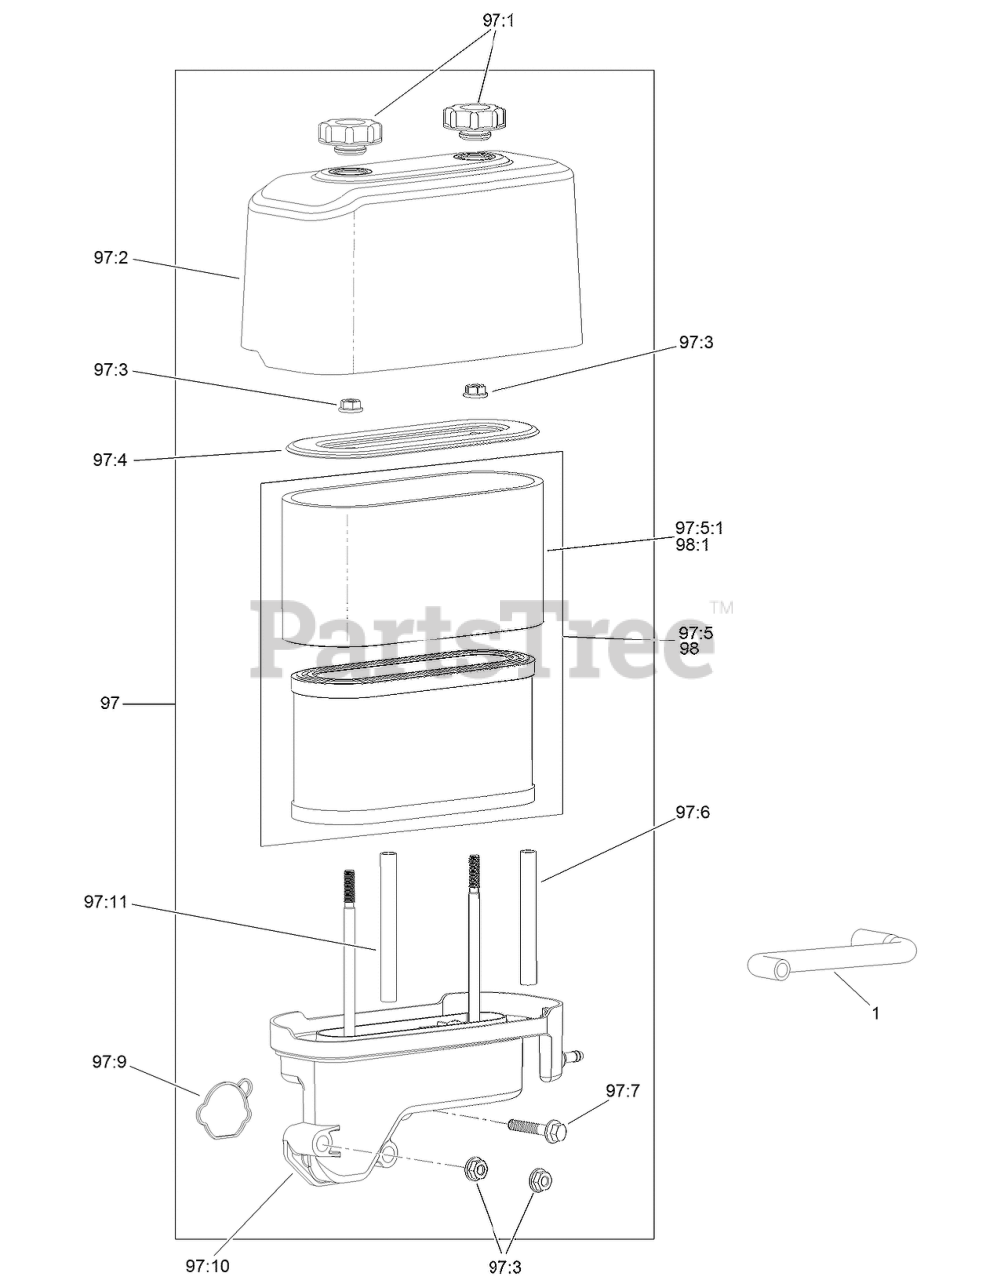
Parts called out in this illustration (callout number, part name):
1	TUBE-BREATHER
97	AIR CLEANER KIT
97:1	NUT-SPEED
97:2	COVER-FILTER, AIR
97:3	NUT-FLANGE
97:4	RETAINER-AIR FILTER
97:5	AIR FILTER KIT
97:5:1	PREFILTER
97:6	SPACER-FILTER, AIR
97:7	SCREW-HHF
97:9	GASKET-CARBURETOR
97:10	BASE-FILTER, AIR
97:11	SPACER-FILTER, AIR
98	AIR FILTER KIT
98:1	PREFILTER
